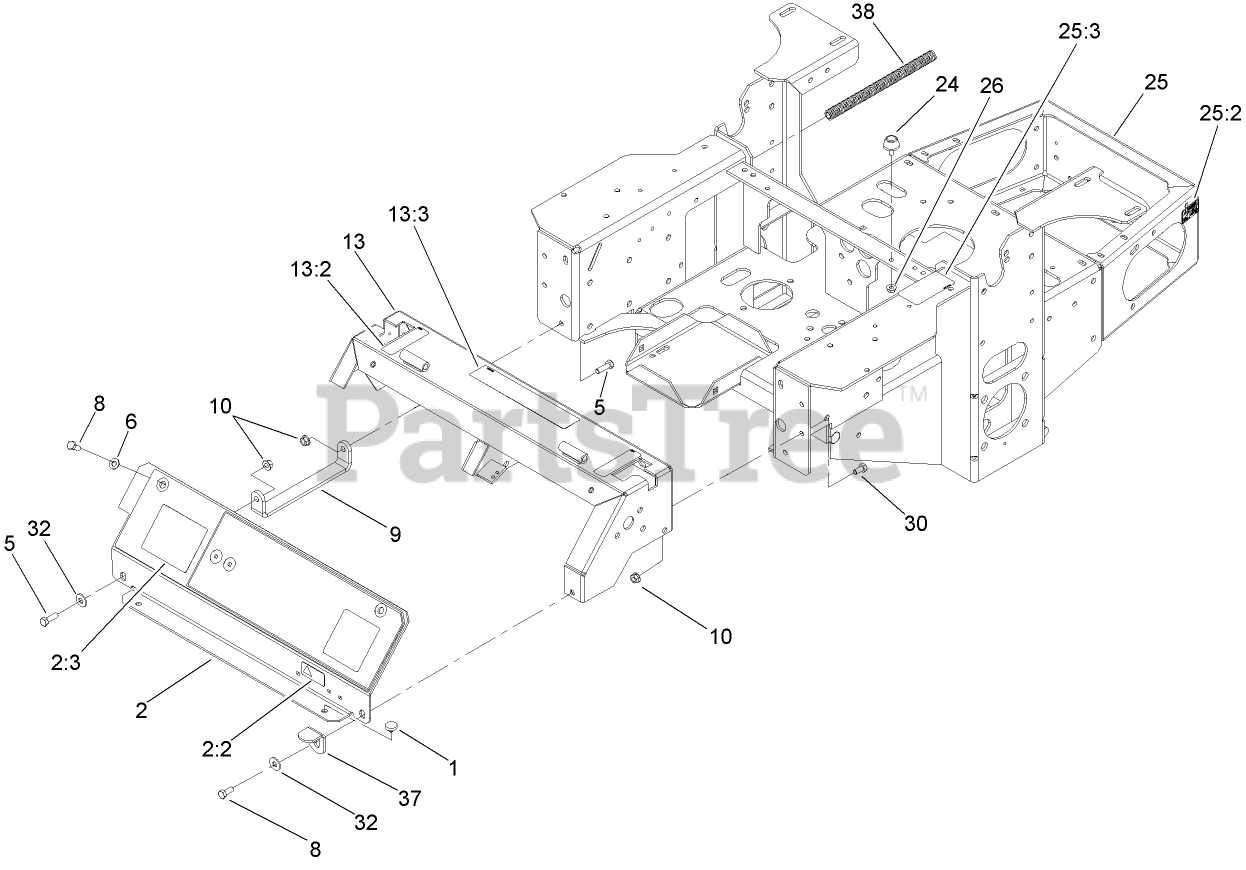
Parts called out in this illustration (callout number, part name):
1	BUMPER
2	PANEL ASM
2:2	DECAL-PROTECTION, EAR
2:3	DECAL-PANEL, COVER
5	SCREW-HH
6	WASHER-PLAIN
8	SCREW-HH
9	BRACKET-PANEL, INSTRUMENT
10	NUT-HF
13	CONSOLE
13:2	DECAL-CONTROL, MOTION
13:3	DECAL-BATTERY
24	BUMPER-RUBBER
25	MAIN FRAME ASM (W/ DECALS CE)
25:2	DECAL-WARNING
25:3	Decal-Release, Drive
26	NUT-HF
30	SCREW-HH
32	WASHER-FLAT
37	STOP-COVER
38	CONDUIT-CONVOLUTED, SPLIT
